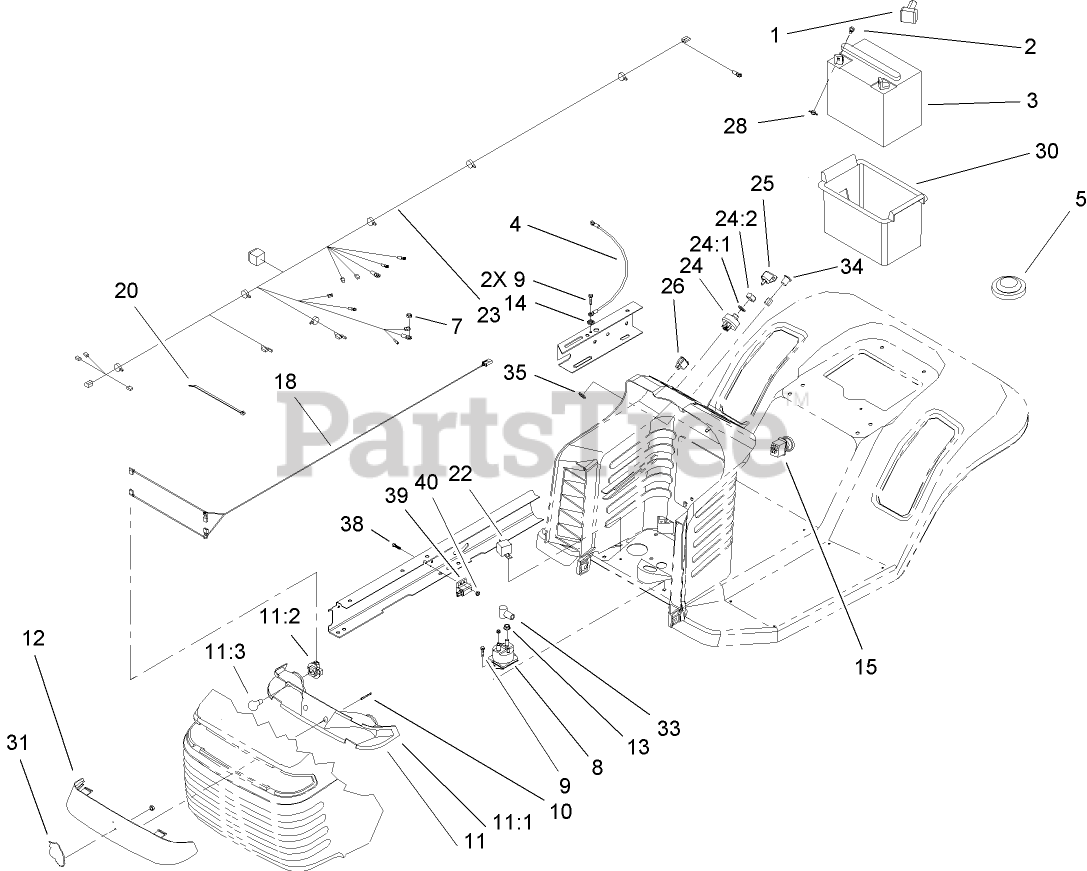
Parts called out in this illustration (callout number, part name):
1	BOOT-TERMINAL
2	SCREW-HH
4	WIRE ASM
5	SWITCH-SEAT
7	NUT-KEPS
8	SOLENOID-STARTER
9	SCREW-HWH
11	HEADLIGHT REFLECTOR ASM
11:1	REFLECTOR-LIGHT
11:2	SOCKET-HEADLIGHT
11:3	BULB
12	LENS-HEADLIGHT
13	NUT-KEPS
14	WASHER-LOCK/EXT
15	SWITCH-PTO,ON-ON-NONE
18	HARNESS-HEADLIGHT
20	TIE-CABLE
22	RELAY
23	HARNESS-WIRE
24:1	WASHER-LOCK
24:2	NUT-HH
25	KEY-IGNITION
26	SWITCH-ROCKER
28	NUT-WING
30	BOX-BATTERY
31	EMBLEM
33	BOOT-INSULATOR, TERMINAL
34	LIGHT-INDICATOR
35	NUT-PUSH-ON, CIRCULAR
38	SCREW-HSH
40	NUT-LOCK, NI
